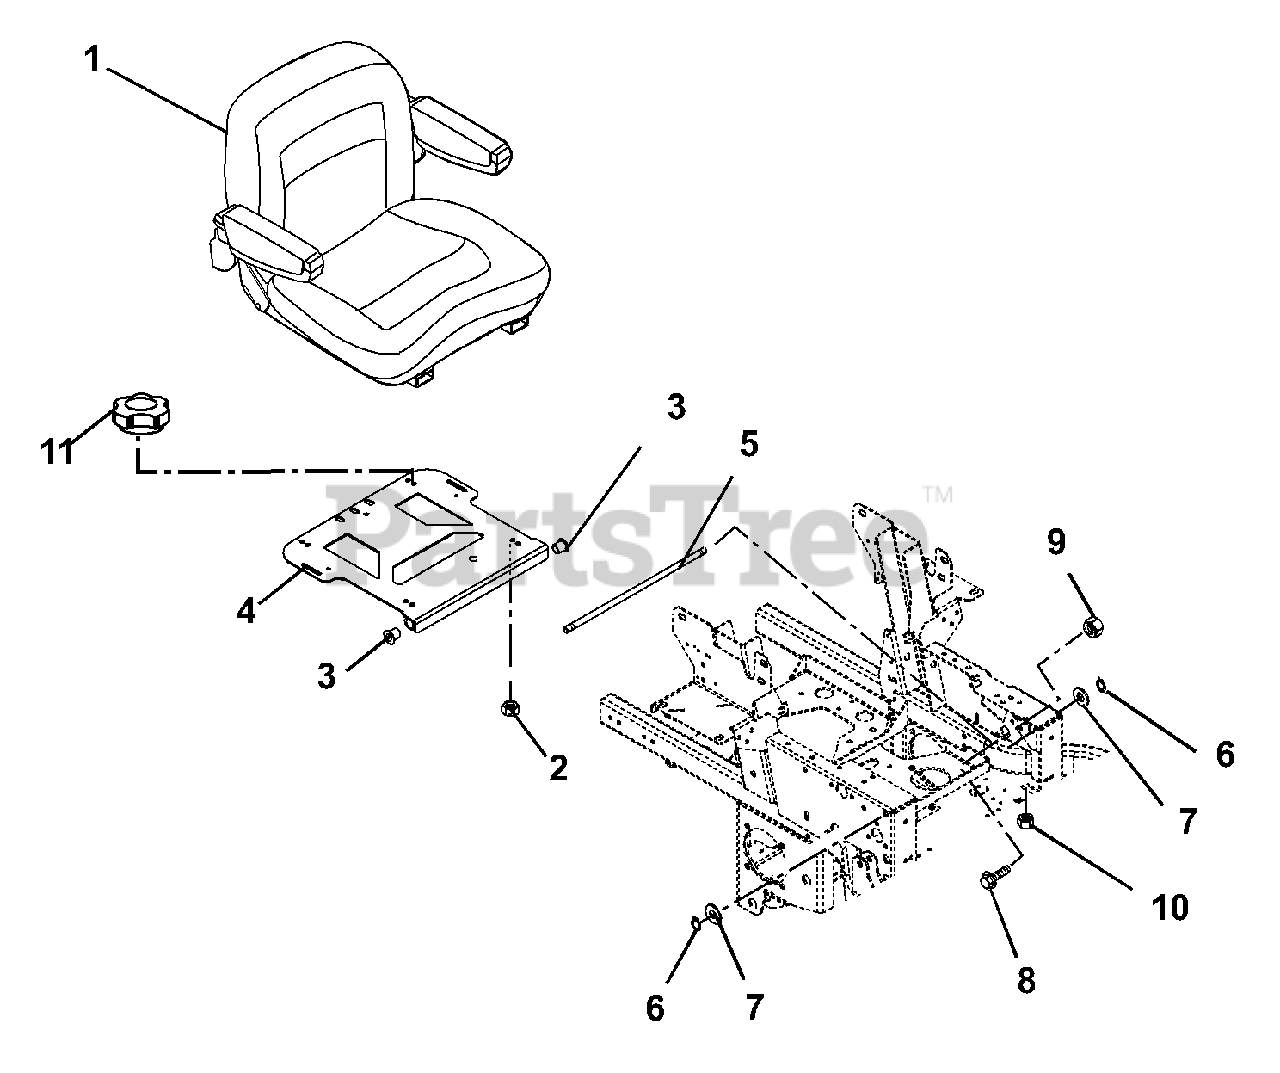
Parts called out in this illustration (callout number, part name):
1	Seat
2	Nut, Locking Top Flange .31-18
3	Bushing, Flange .515 x .750 x .745 x 1.00
4	Seat Pivot Mount
5	Rod, Seat Frame Pivot
6	Ring, Retaining External .500 x .050
7	Washer, Thrust .531 x 1.00 x .063
8	Bolt, Shoulder EP .38-16 x .30 Hex
9	Nut-Locking-Center .38-16
10	Nut, Locking Top Flange .25-20
11	Knob, Clamping .312-18 Nyloc
